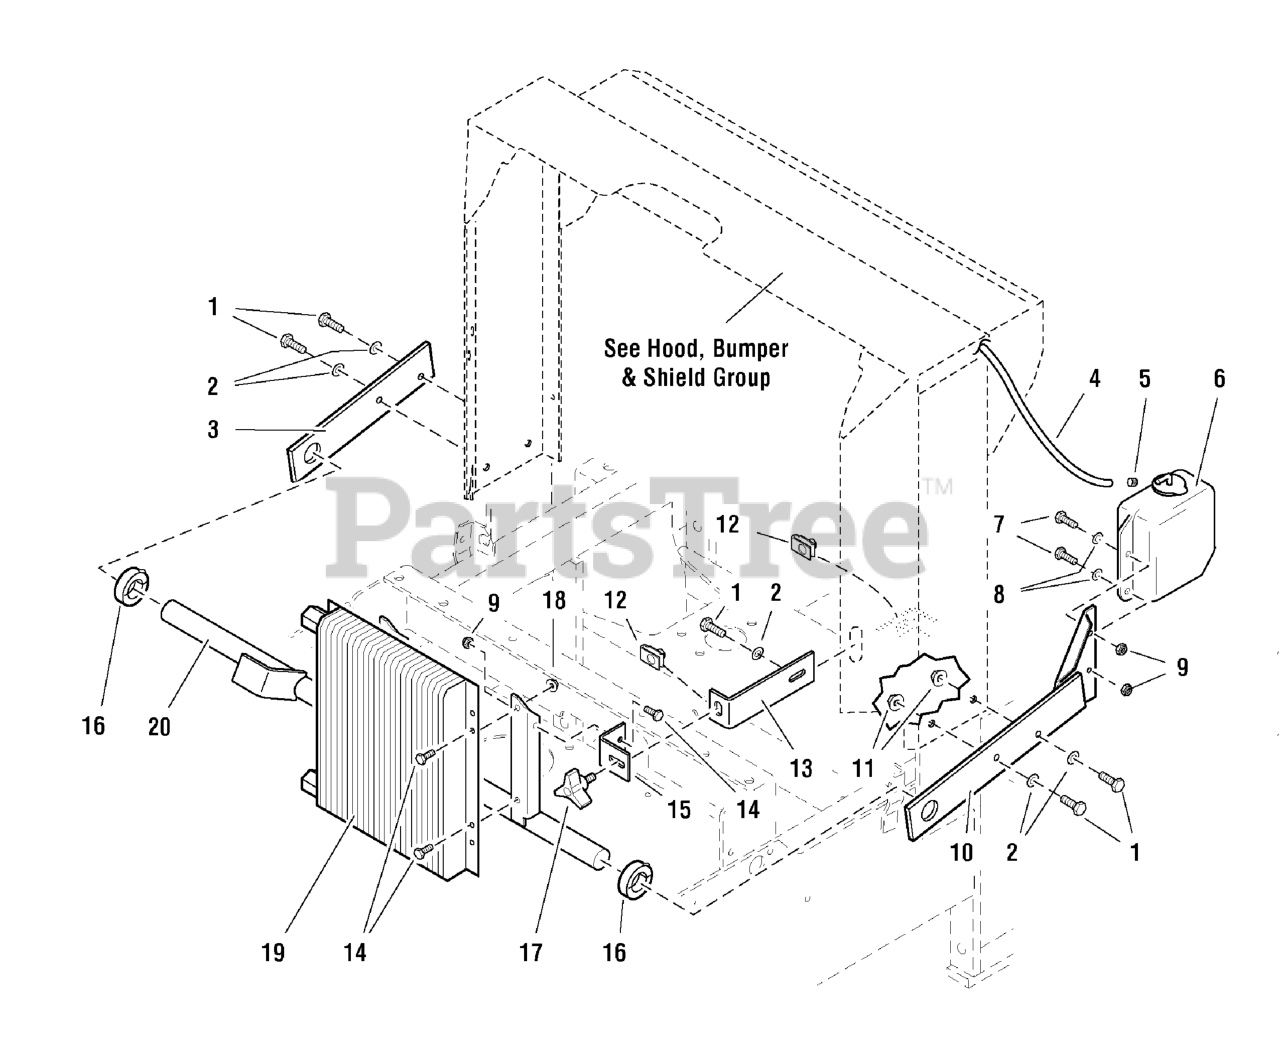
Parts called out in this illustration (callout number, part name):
1	BOLT, 5/16-18 X 1 GD5 YZ
2	WASHER, 3/8 SAE
3	OIL COOLER PIVOT PLATE
4	OVERFLOW HOSE
5	CLAMP, Hose
6	EXPANSION TANK, Complete
7	BOLT, 1/4-20 X 1" GD5 CZ
8	WASHER, 1/4 SAE
9	NUT, 1/4-20 HEX NYLON LOCK
10	OIL COOLER MOUNT PLATE-LH
11	NUT, 5/16-18 HEX SERRATED FLANGE (LARGE)
12	BODY CLIP, 5/16-18-7GA MATERIAL
13	COOLER PIVOT ANCHOR
14	SCREW, Allen Head, 1/4-20 x 1/2
15	COOLER LOCK BRACKET
16	COLLAR, 1" Split
17	KNOB
18	NUT, 1/4-20 HEX SERR. FLANGE
19	OIL COOLER
20	OIL COOLER MOUNT
